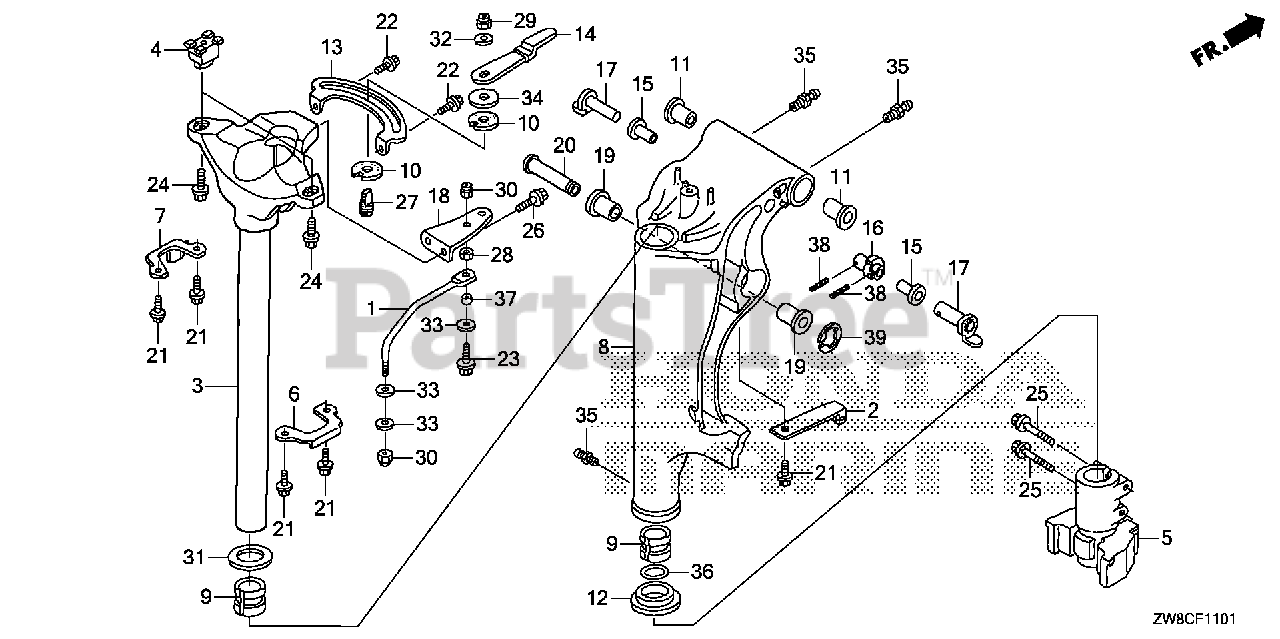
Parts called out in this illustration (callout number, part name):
2	SPRING, CLICK
3	FRAME, MOUNTING (L)
4	RUBBER, MOUNTING (UPPER)
5	RUBBER, MOUNTING (LOWER)
6	COVER, MOUNTING RUBBER (UPPER)
7	COVER, MOUNTING RUBBER (UPPER) (PT)
8	CASE, SWIVEL *NHB14M* (L)(PT) (AQUA MARINE SILVER METALLIC)
9	LINER, SWIVEL CASE
10	BLOCK, FRICTION
11	BUSH, SWIVEL CASE
12	COLLAR, SWIVEL CASE
13	PLATE, FRICTION
14	LEVER, FRICTION
15	BUSH, TILT ARM
16	BRACKET, TILTING
17	STOPPER, TILT
19	BUSH, CYLINDER (LOWER)
20	PIN, CYLINDER (UPPER)
21	BOLT, FLANGE (6X12) Use from Frame SN 1005249.
22	BOLT, FLANGE (6X12)
24	BOLT, FLANGE (10X25)
25	BOLT, FLANGE (8X45)
27	BOLT, STUD (8X26)
29	NUT, SELF-LOCK (8MM)
31	WASHER, THRUST
32	WASHER (8MM)
34	WASHER, NYLON (8MM)
35	NIPPLE, GREASE
36	O-RING (34X2.4)
38	PIN, SPRING (2.5X20)
39	E-RING (15MM)
